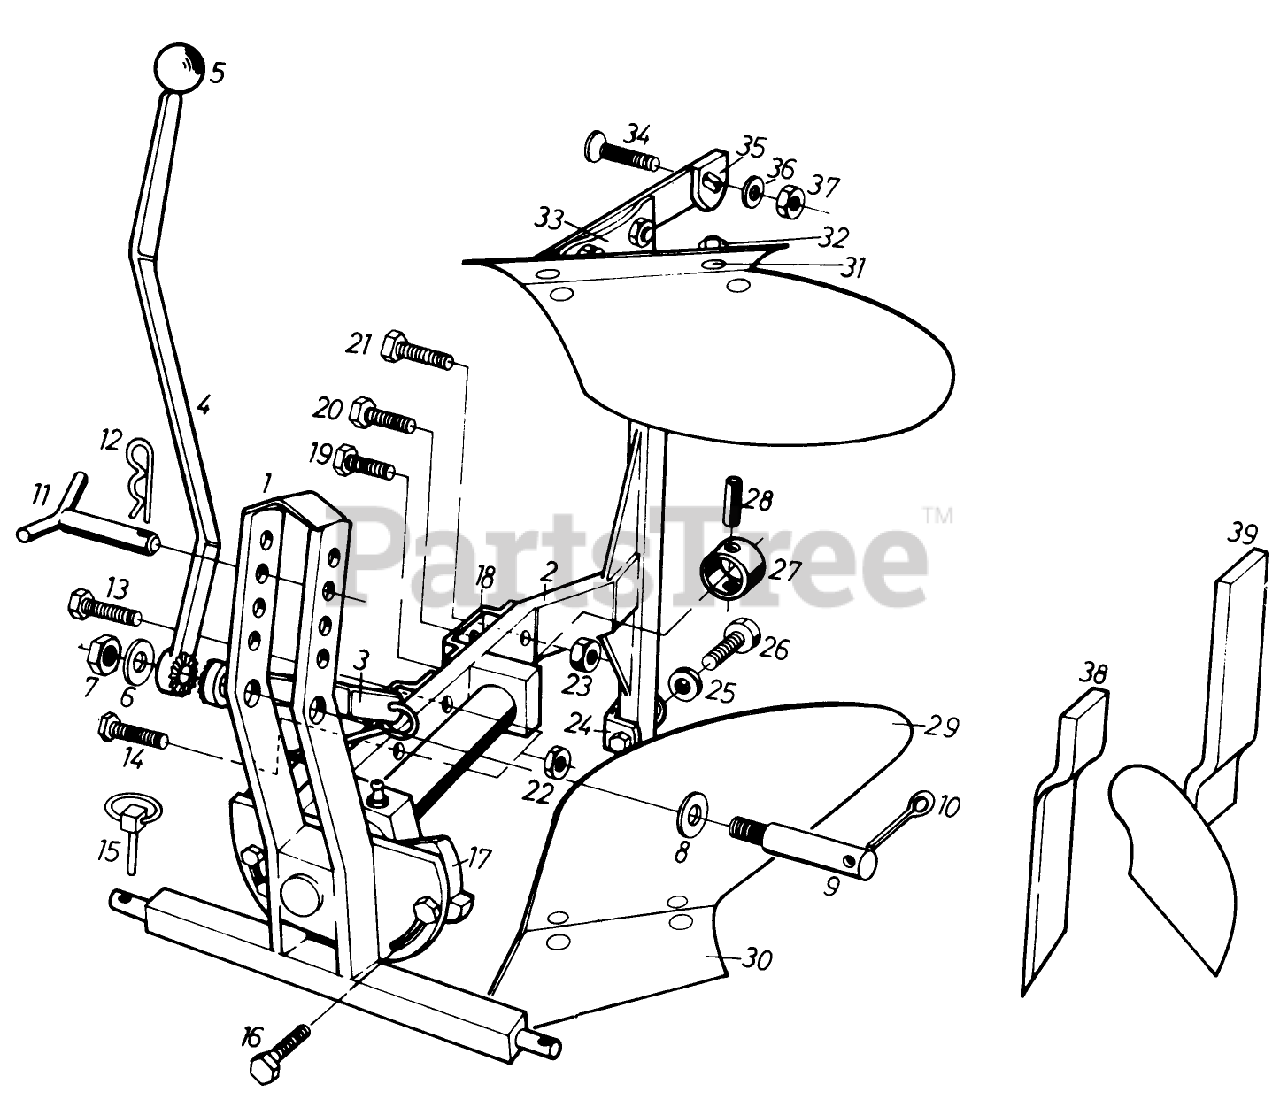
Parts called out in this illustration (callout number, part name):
1	Head Stock
2	Frame
6	Washer
7	Hex Nut
8	Washer
9	Pivot Pin
10	Cotter Pin
11	Upper Link Pin
12	Hairpin Cotter
13	Hex Bolt
14	Hex Bolt
15	Klik Pin
18	Coulter Clamp
19	Hex Bolt
20	Hex Bolt
21	Hex Bolt
22	Hex Nut
23	Hex Nut
24	Clamp
25	Hex Nut
26	Hex Bolt
27	Bushing
28	Roll Pin
29	Mold Board
30	Share
31	Plow Bolt
33	Share Bracket
35	Landslide
36	Washer
38	Coulter (Small)
39	Coulter (Large)
